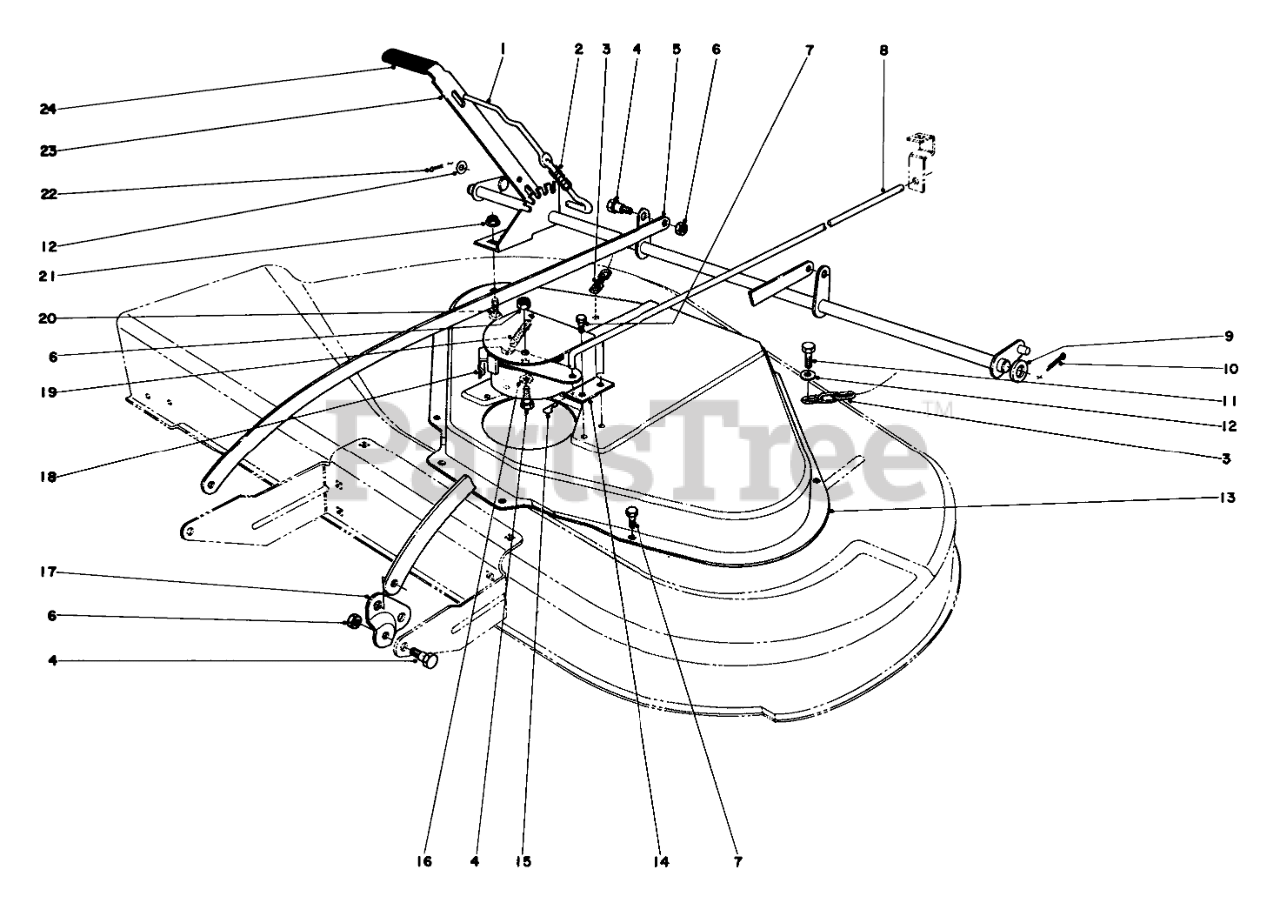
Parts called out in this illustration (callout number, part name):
1	Latch Slide
2	Spring
3	Chain
4	Screw
5	Lift Bar
6	Nut
7	SCREW-HWH
8	Brake Rod
9	WASHER
10	PIN-COTTER
11	SCREW-HWH
12	WASHER-FLAT
13	Housing Cover
14	Belt Guard
15	PIN-COTTER
16	WASHER-FLAT
17	Pivot
18	Brake Lever
19	Spring
20	SCREW-CARR
21	NUT-HF
22	PIN-COTTER
23	Height Adj. Shaft
24	Grip Handle
